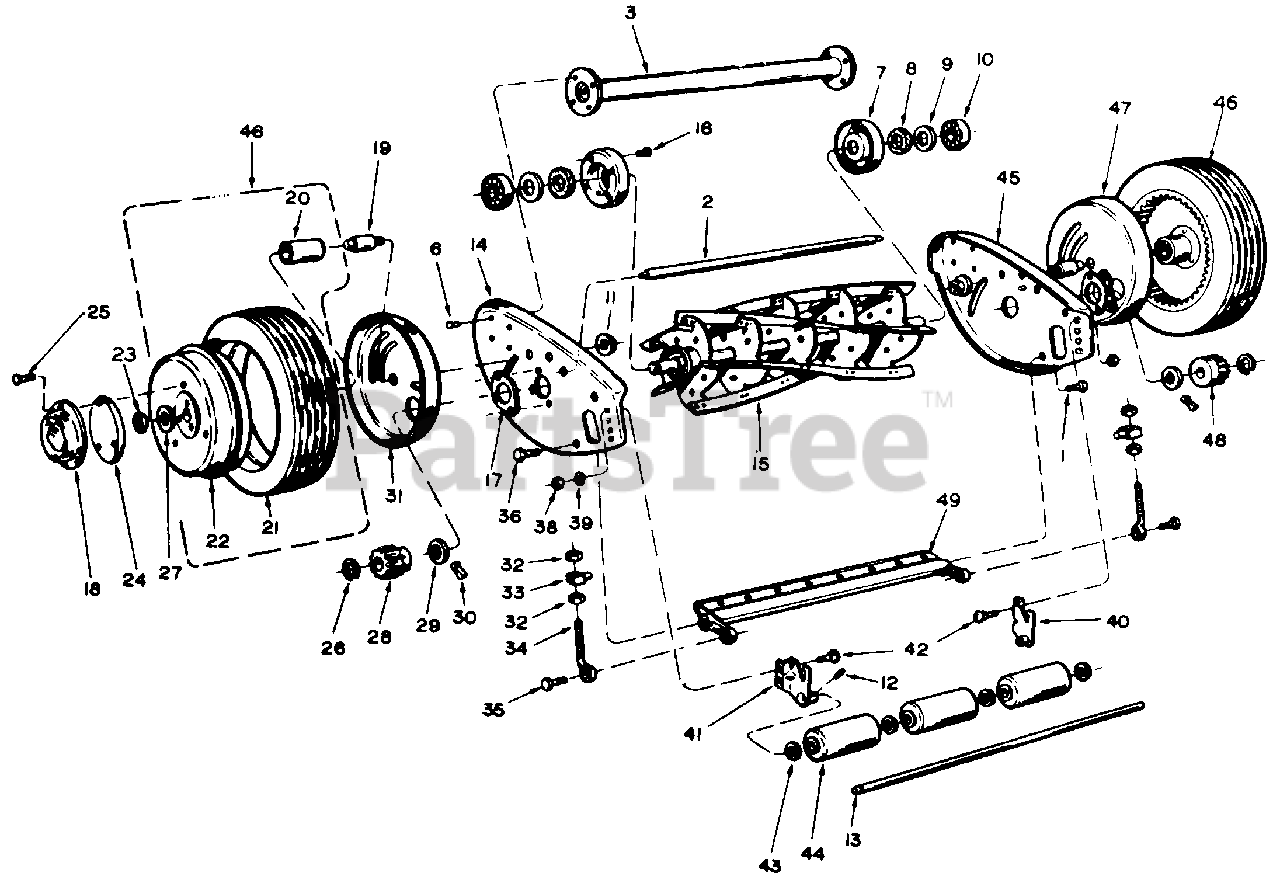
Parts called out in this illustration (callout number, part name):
1	Screw Front L.H. Thd.
2	Spacer End Plate
3	Spacer Tube Ass'y.
6	Rivet 3/16 x 3/8 Rd. Hd.
7	Retainer
8	Felt Washer
9	Felt Retainer
10	Bearing
11	Nut-Special
12	Roll Pin
13	Roller Shaft
14	End Plate Trunnions-L.H.
15	Reel Ass'y.-21 "
16	Rivet 3/16 x 13/32 Rd. Hd.
17	Bearing Retainer
18	Hub Cap
20	Bearing
21	Ti re
22	DriveWheel-LessTire
23	Retaining Ring
24	Wheel Weight
25	Scr. #10-32 x 1-3/8 Thd. Cutting
26	Retaining Ring
27	Washer
28	Pinion Gear-L.H.
29	Felt Washer
31	Gear Housing-L.H.
32	Hex Nut 3/8-24 Semi Fin
33	Trunnion
34	Cutter Bar Adjusting Bolt
35	Screw-Rear
36	Screw-Front R.H. Thd.
38	Nut 5/8-18
39	L. Wash. 5/16" I.D.
40	Roller Brkt.-R.H.
41	Roller Brkt.-L.H.
42	Carr. Bolt 5/16-18 x 1
43	Washer 1/2 x 1 1/16
44	Roller-3 Required
45	End Plate with Trunnions-R.H.
46	Drive Wheel Ass'y. w/tire
47	Gear Housing-R.H.
48	Pinion Gear-R.H.
49	Cutter Bar Ass'y.
